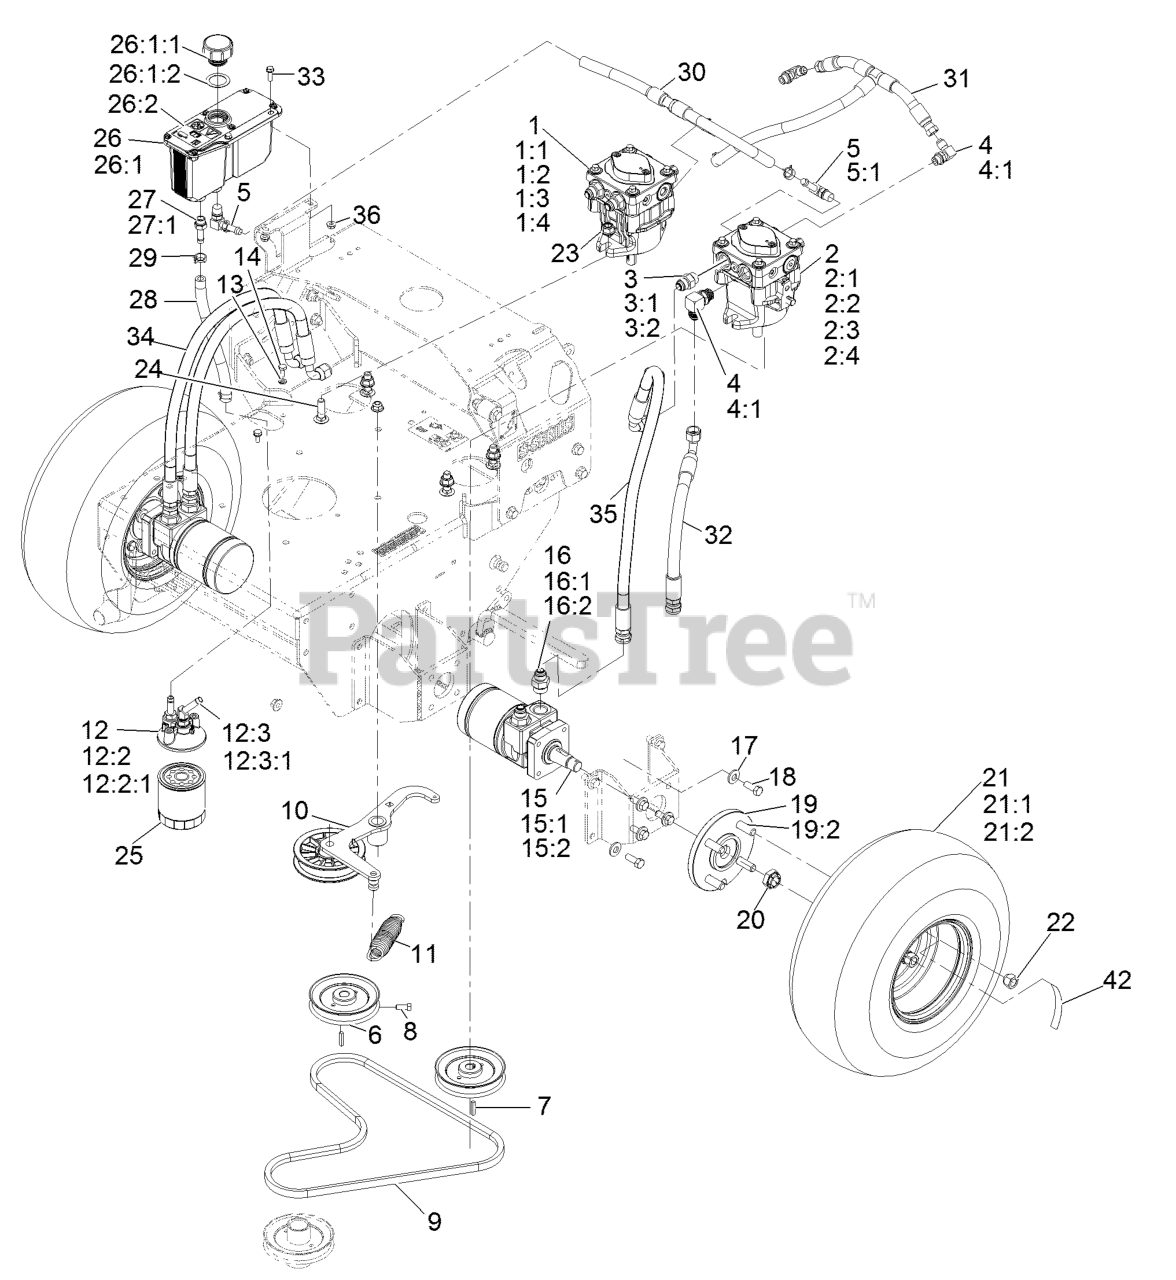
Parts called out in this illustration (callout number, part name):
1	RH HYD PUMP ASM
1:1	INPUT SHAFT KIT
1:2	BEARING-THRUST
1:3	CYLINDER BLOCK KIT
1:4	SEAL OVERHAUL KIT
2	LH HYD PUMP ASM
2:1	INPUT SHAFT KIT
2:2	BEARING-THRUST
2:3	CYLINDER BLOCK KIT
2:4	SEAL OVERHAUL KIT
3	FITTING-STRAIGHT
3	FITTING-90 DEG
4	FITTING-ELBOW, 90 DEG
5	FITTING-ELBOW, 90
5:1	O-RING
6	SHEAVE ASM
8	SCREW-SET, SQH
9	BELT
10	ASM, PUMP IDLER
11	SPRING-EXTENSION
12	ASM, FILTER HEAD
12:2	ADAPTER-STRAIGHT
12:2:1	O-RING
12:3	FITTING-BARBED, 45 DEG
12:3:1	O-RING
13	WASHER-LOCK
14	SCREW-HH
15	HYD MOTOR ASM
15:1	SEAL KIT
15:2	BEARING AND SEAL KIT
16	FITTING-STRAIGHT
16:1	O-RING
17	WASHER-BELLEVILLE
18	SCREW-HH
19	WHEEL HUB ASM
19:2	STUD-WHEEL
20	NUT-LOCK
21	WHEEL AND TIRE ASM
21:1	TIRE-TURFMASTER
21:2	RIM-WHEEL
22	NUT-LUG
23	NUT-HF, NI
24	SCREW-HH
25	FILTER-25 MICRON, BI-DIRE
26:1	Reservoir-HYD
26:1:1	Cap-Reservoir, HYD
26:1:2	GASKET-CAP
26:2	DECAL-WARNING
27	ADAPTER-STRAIGHT
27:1	O-RING
28	HOSE-CHARGE
29	CLAMP-HOSE
30	HOSE-CASE DRAIN
31	HOSE-CHARGE
32	ASM, HP HOSE
33	SCREW-HWH
34	HYD HOSE ASM
35	HYD HOSE ASM
42	DECAL-TORQUE WHEEL LUG-HU
